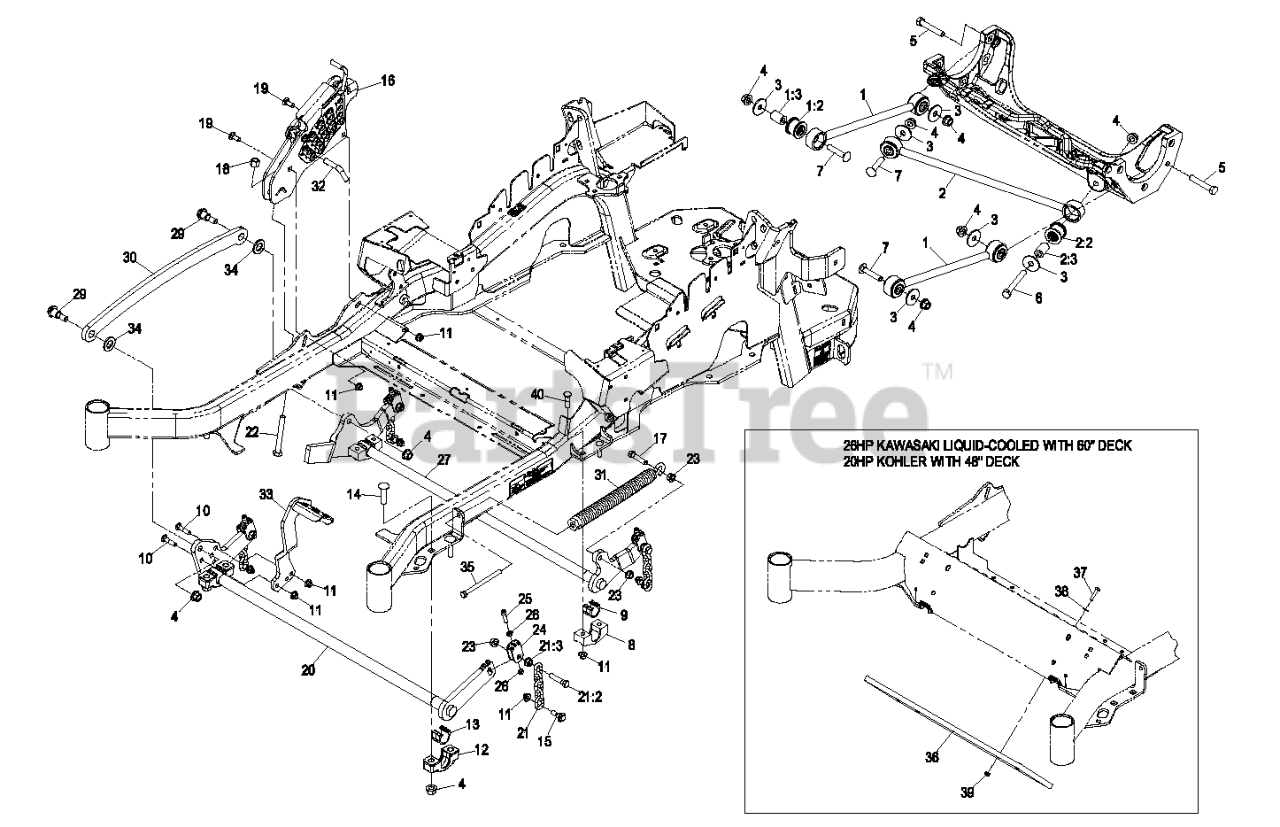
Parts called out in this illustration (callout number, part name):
1	DECK STRUT ASM
1:2	BUSHING-SUSPENSION, RUBBER
2	PANHARD ROD ASM
2:2	BUSHING-SUSPENSION, RUBBER
3	WASHER-THRUST
4	Nut-Lock 1/2-13
5	SCREW-HH
6	SCREW-HH
7	SCREW-CARR
9	BEARING-CROSS SHAFT, REAR
10	SCREW-CARR
11	NUT-HF, NI
12	SUPPORT-CROSS SHAFT, BEARING
13	BEARING-CROSS SHAFT, FRON
14	SCREW-CARR
15	SCREW-SHOULDER, HHF
16	HOC ASM
17	SCREW-HH
18	NUT-LOCK, NI
19	BOLT-CARR
21	DECK LIFT CHAIN ASM
22	BOLT-TAP
24	YOKE-ADJUST, DECK
25	SCREW-HSH
26	NUT-JAM
27	LIFT-DECK, REAR
29	SCREW-SHOULDER, HHF 1/2-13 X 1.12
30	LINK-LIFT, DECK
31	SPRING-EXTENSION
32	PIN-HOC
33	LEVER-FOOT
34	WASHER-FLAT
35	BOLT-TAP, HH
36	WEIGHT,TOE BOARD
37	SCREW-HH
38	WASHER-FLAT
40	SCREW-CARR
